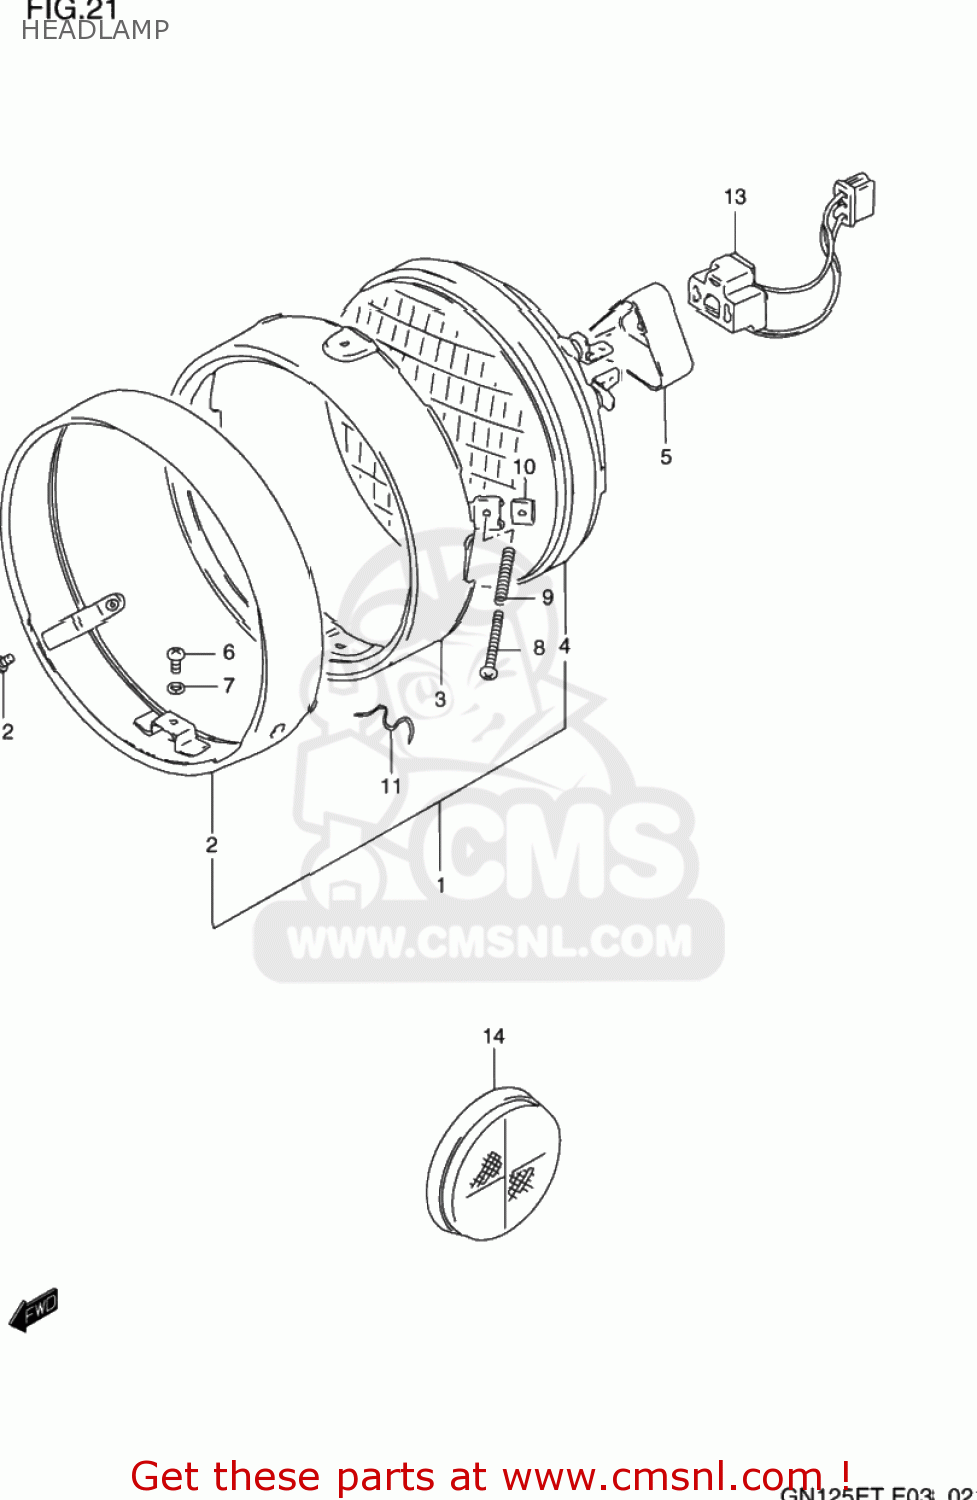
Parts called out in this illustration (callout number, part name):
1	LAMP ASSEMBLY,HEAD
2	RIM
3	RETAINER
4	LAMP UNIT
5	COVER
6	SCREW
7	LOCK WASHER
8	SCREW
9	SPRING
10	NUT
11	SPRING,HEAD LAMP UNIT
12	SCREW
13	LEAD WIRE,HEADLAMP
14	REFLEX REFLECTOR,RR
